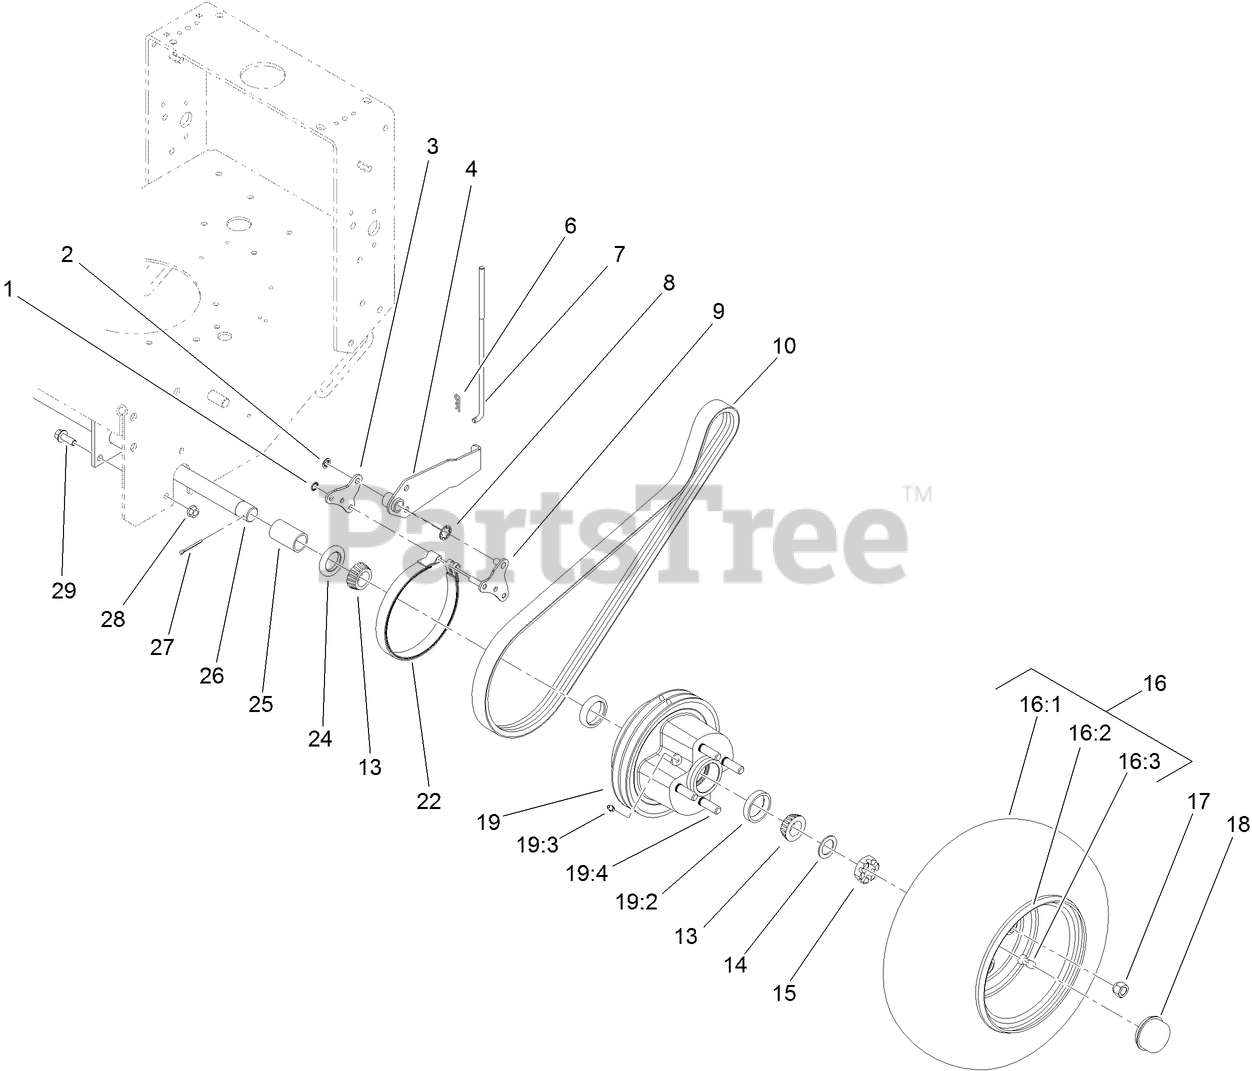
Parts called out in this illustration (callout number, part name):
1	RING-RETAINING
2	RING-RETAINING, EXTERNAL
3	PLATE-LINK, BRAKE
4	ARM-BRAKE
6	PIN-COTTER
7	ROD-BRAKE
8	RING-RETAINING
9	BRAKE LINK ASM
10	BELT-V, BANDED
13	BEARING-ROLLER, TAPERED
14	WASHER-SPACER
15	NUT-SHH
16	WHEEL AND TIRE ASM
16:3	STEM-VALVE
17	NUT-LUG
18	CAP-DUST
19	WHEEL HUB ASM
19:2	CUP-BEARING
19:3	FITTING-GREASE
19:4	STUD-TYPE, DRIVE
22	BAND-BRAKE
24	SEAL-GREASE
25	SPACER-WHEEL
27	PIN-COTTER
28	NUT-HF
29	SCREW-HHF
